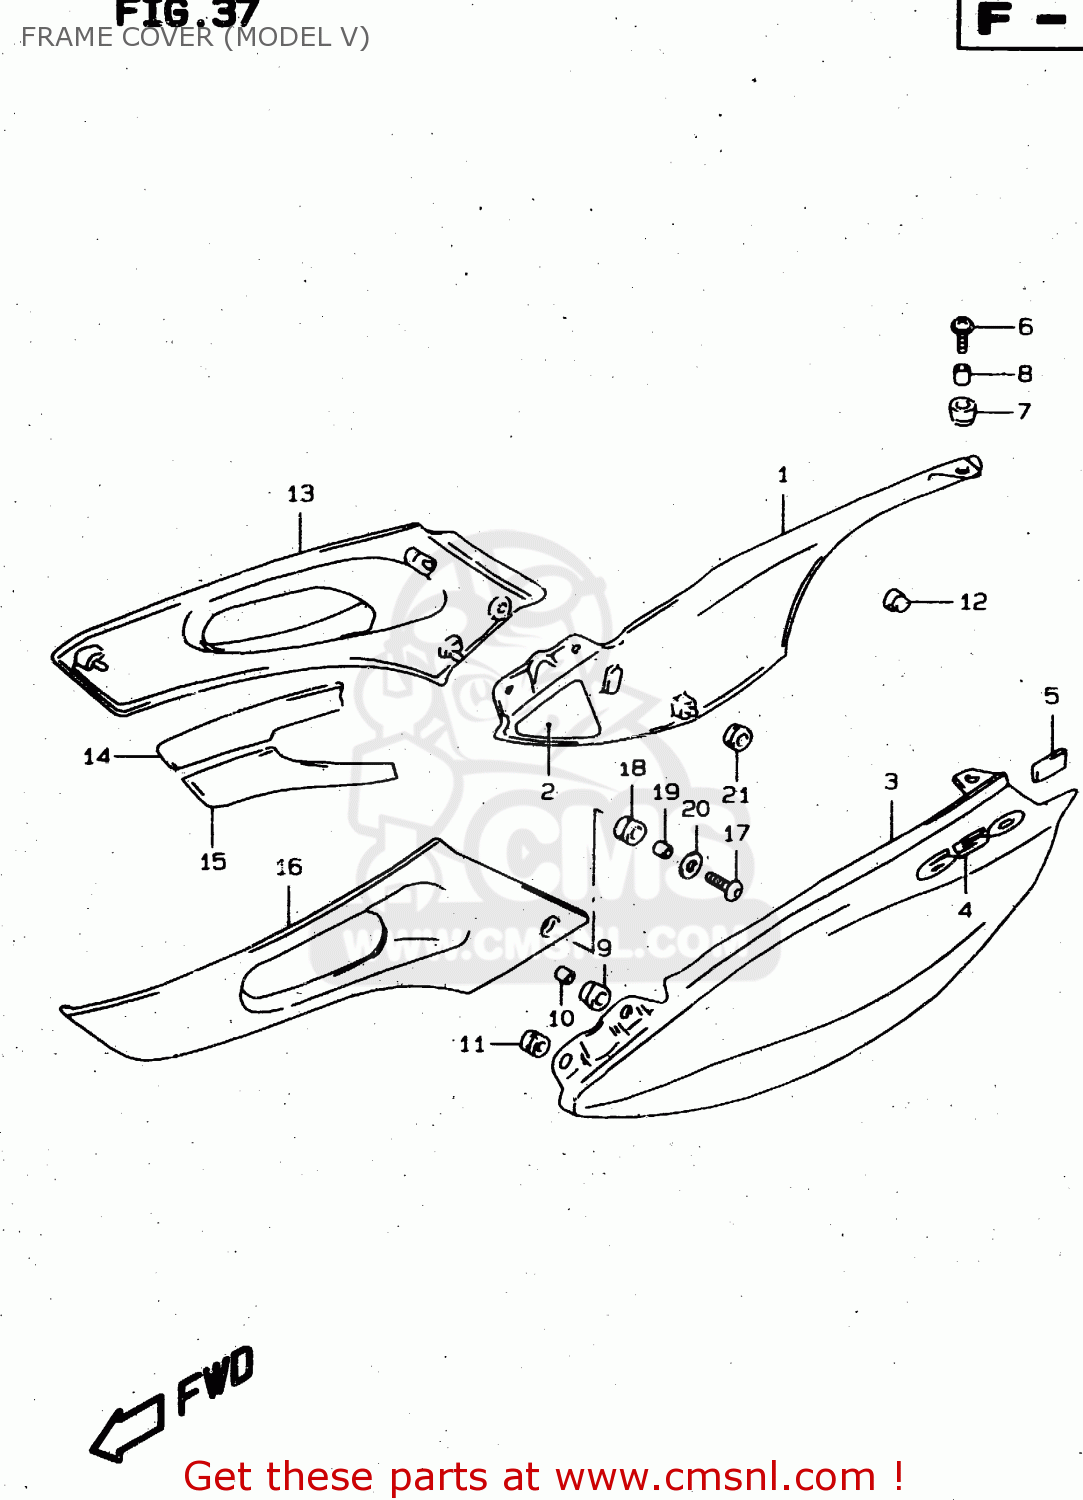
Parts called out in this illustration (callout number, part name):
1	COVER,FRAME,R
2	SHIELD,FRAME COVER,R
3	COVER,FRAME,L.
4	EMBLEM,FRAME COVER
5	CUSHION,FR FENDER
6	SCREW(6X20)
7	CUSHION
8	SPACER(6.5X10X9.4)
9	CUSHION
10	SPACER(6.5X9X9)
11	CUSHION
12	CUSHION
13	COVER,FRAME FR,R
14	SHIELD, FRONT RH UPPER
15	SHIELD, FRONT RH LOWER
16	COVER,FRAME FR,L
17	SCREW(6X30)
18	CUSHION
19	SPACER(6.5X9X9)
20	WASHER
21	CUSHION
